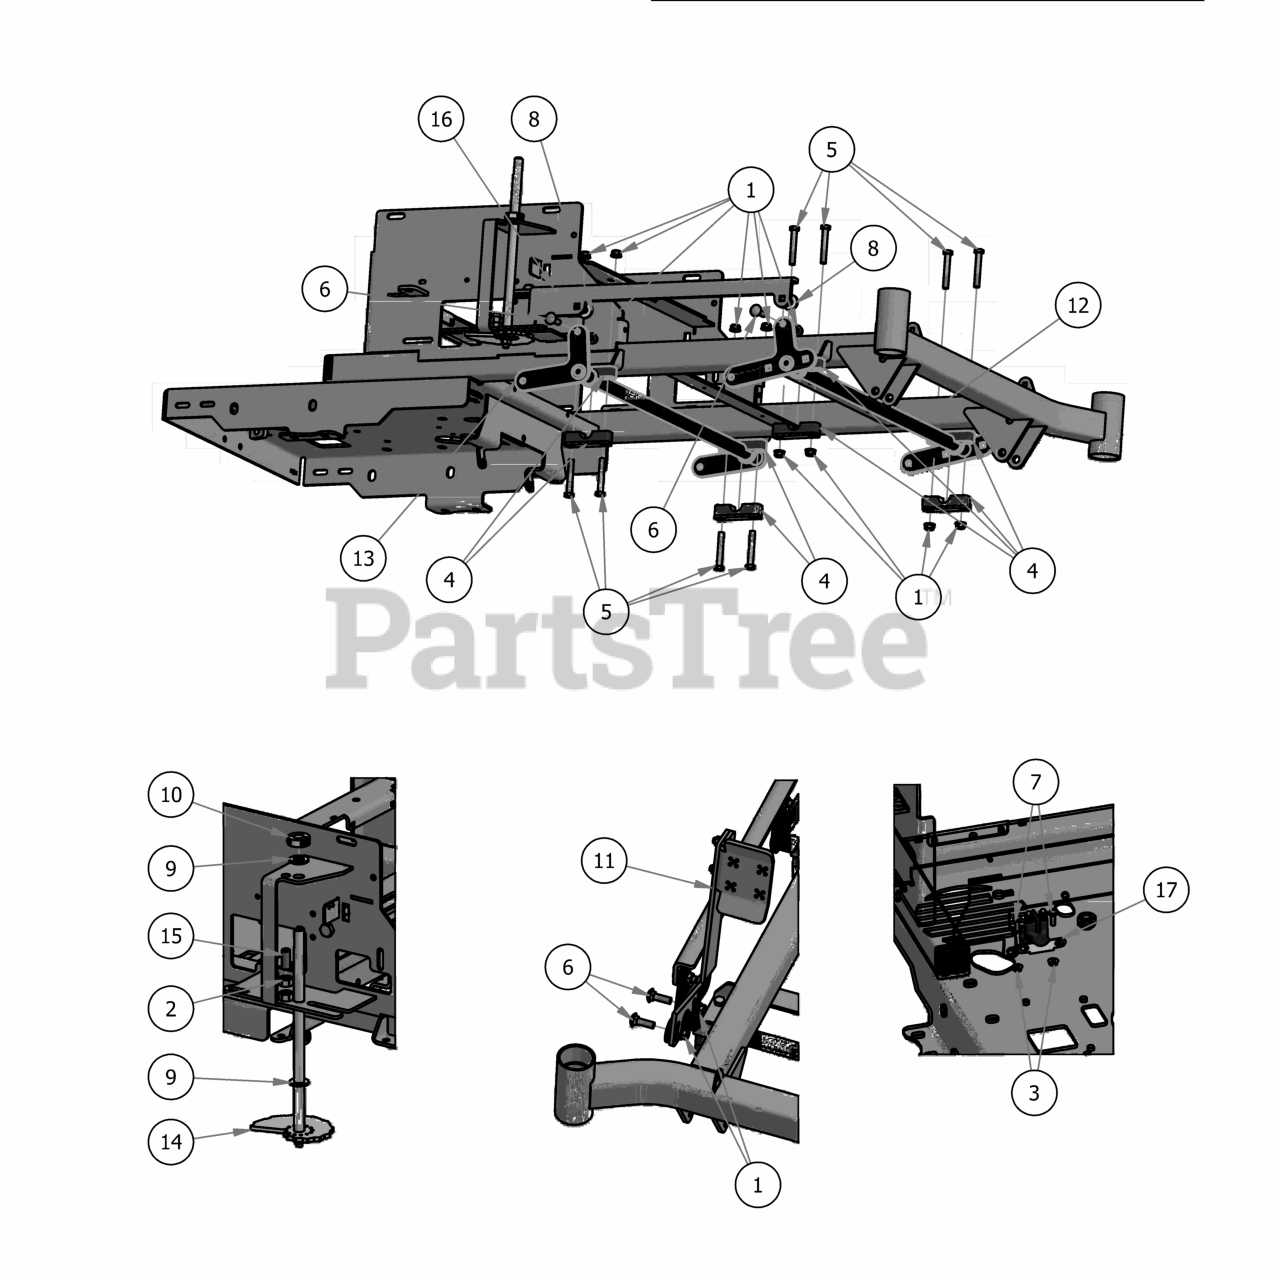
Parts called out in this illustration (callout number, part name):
1	3/8" Nylock Flange Nut
2	1/2" Hex Nut
3	1/4-20 Hex Flange Nuts Zinc w/Serrations
4	Pillow Block Kit
5	3/8-16 x 2 1/2" Hex Bolt
6	3/8" x 1 1/4" Carriage Bolt
7	1/4" x 3/4" Hex Bolt
8	.390 ID Plastic Washer
9	.630 ID x 1.122 OD x .142 THK Plastic Washer
10	5/8" Split Collar
11	Foot Pedal Assembly
12	Actuator Bar Front- 2017 MZ/ZT
13	Actuator Bar Rear- 2017 MZ/ZT
14	Deck Height Dial Rod Assembly
15	Dial Rod Plunger
16	2017 MZ/ZT Actuator Linkage
